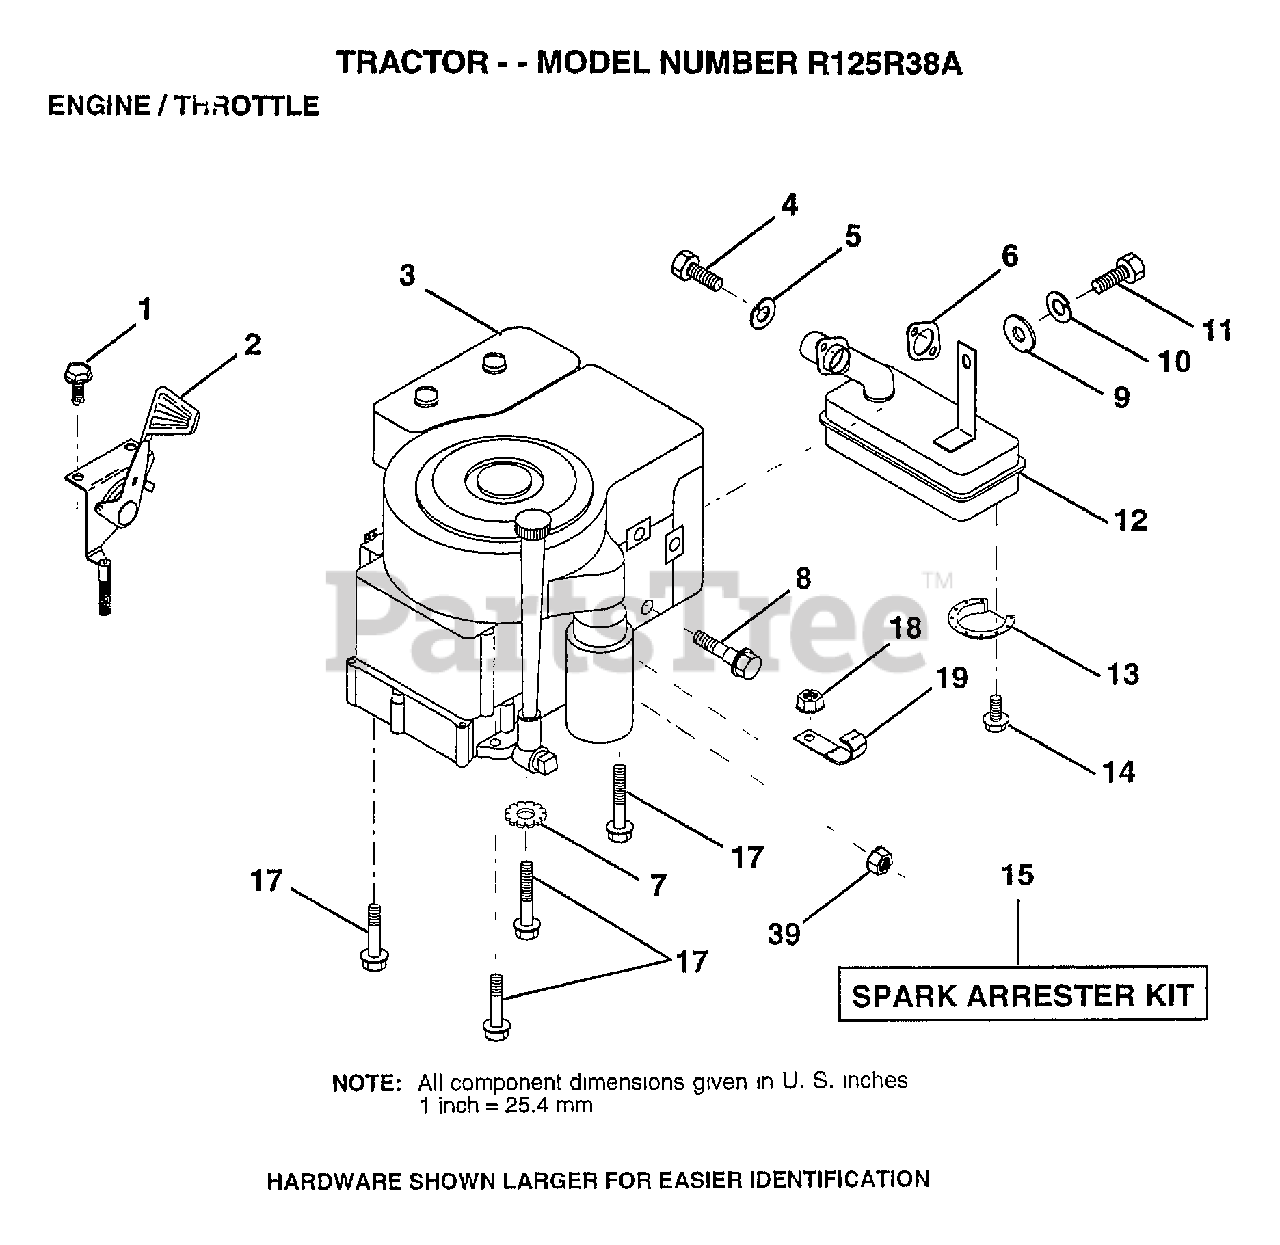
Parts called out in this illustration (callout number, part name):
1	SCREW.1/4-20X1/2
2	"CONTROL,THROTTLE"
4	SCREW
5	LOCKWASHER
6	GASKET ENG 1 313 LD TIN PLATED
7	LOCKWASHER
8	BOLT T
10	LOCKWASHER
12	MUFFLER
13	DEFLECTOR.222573
17	SCREW LT
18	NUT
19	CLIP T
39	NUT
